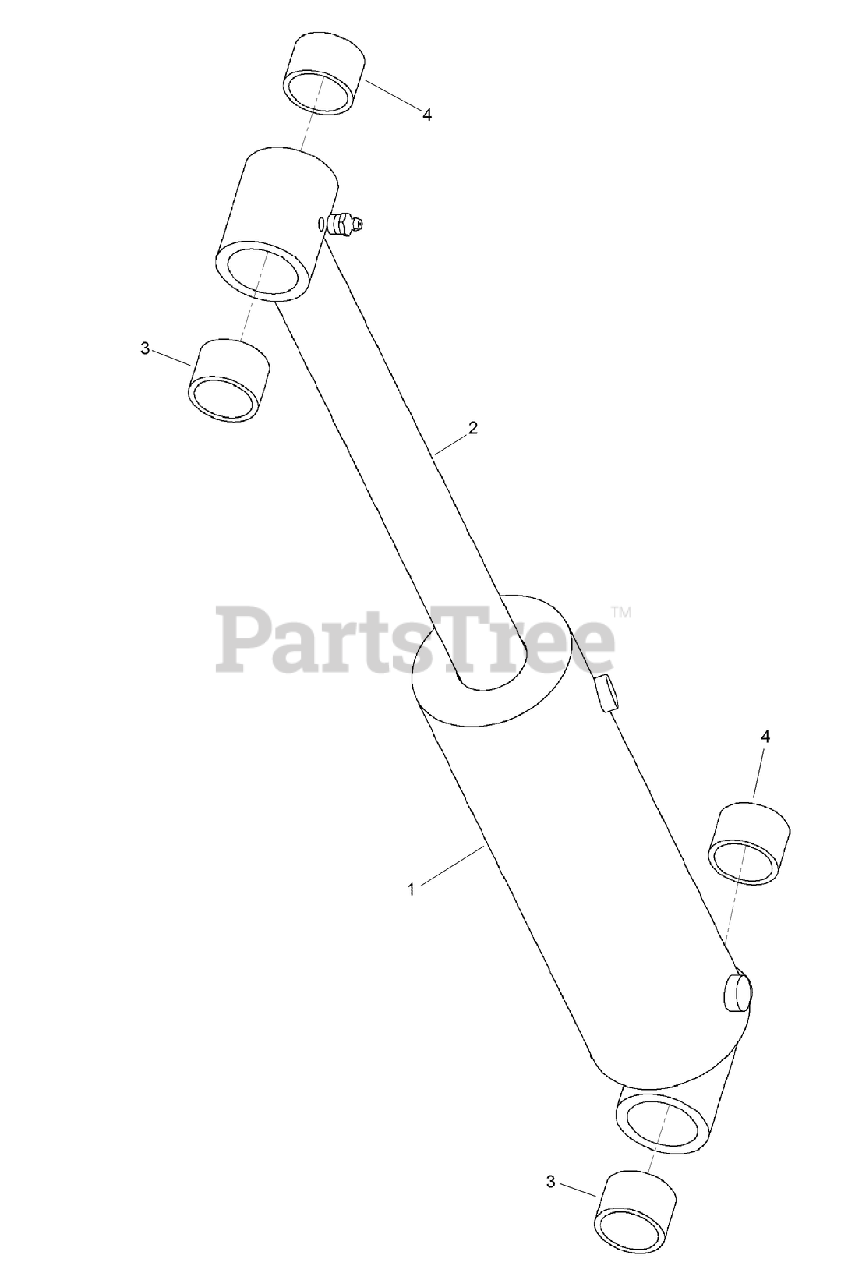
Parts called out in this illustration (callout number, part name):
1	TUBE-swing cylinder
2	ROD-PISTON
3	BUSHING-ROD END, CYLINDER
4	FITTING-Lube, 1/8-27 Dryseal PTF
